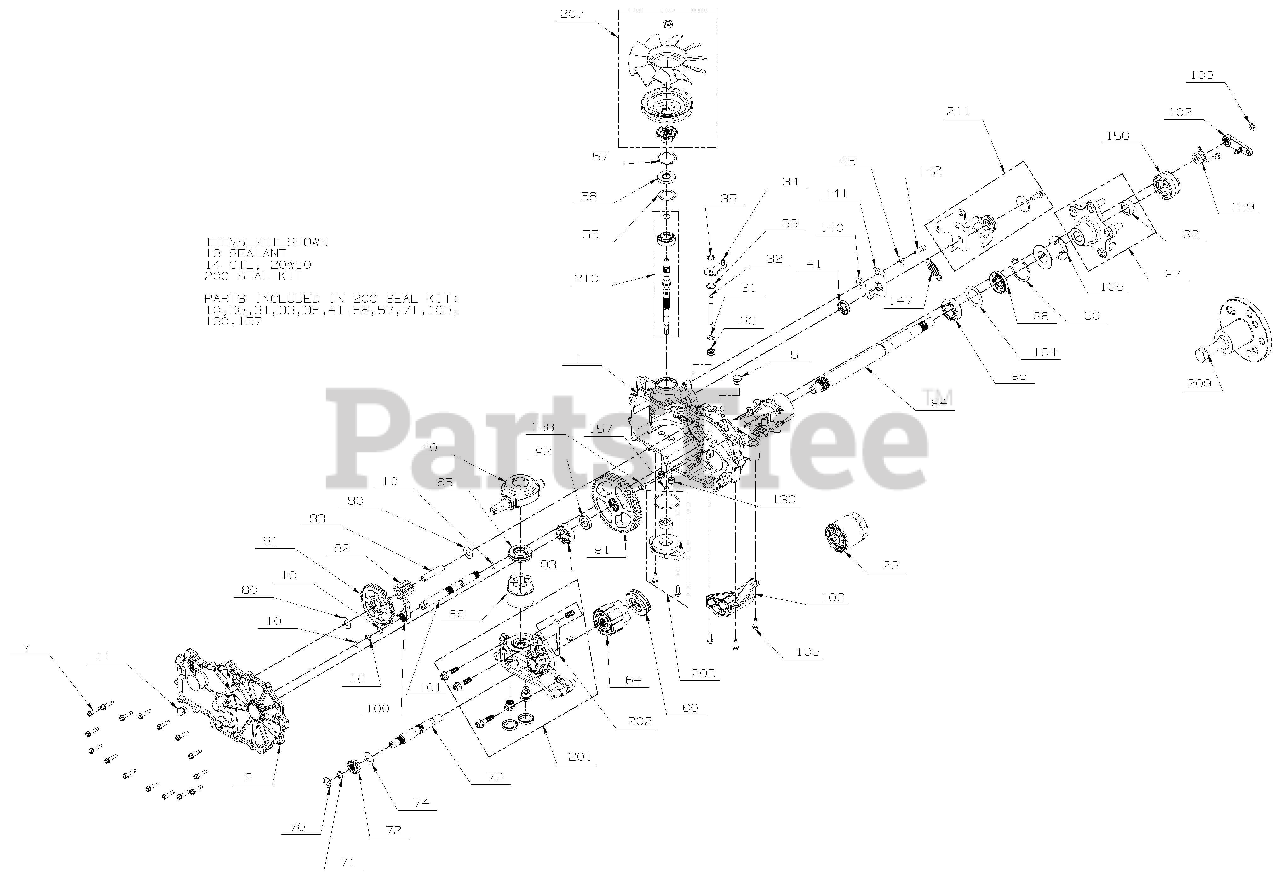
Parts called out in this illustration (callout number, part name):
1	KIT, MAIN HOUSING, RH, CHARGE, CONTROL
2	KIT, SIDE COVER RH
7	SCREW,HEX WASHER 1/4-20X1.125
13	SEALANT TUBE 10.1OZ.
23	OIL FILTER, TRANSMISSION
30	SEAL, LIP .375X.75X.25
31	RING. RETAINING
33	RING, RET .750
34	ARM, BYPASS
35	RING, RTNG .
40	TRUNNION, SWASHPLATE
41	SEAL, LIP 18X32X7
45	WASHER
55	WASHER 1.23X1.56X.04
56	SEAL, LIP 17X40X7
57	RING, RET 1.56 INT
60	HG THRUST BEARING (51462)
64	HG 16CC CYLINDER BLOCK (71579)
65	HG THRUST BLOCK (53502)
69	HG SEVEN PISTON BLOCK (71971)
70	WASHER .63X1.0X.05
71	RING, RET 62 EXT
73	SHAFT, MOTOR
74	WASHER .71 X 1.16 X .04
80	WASHER .5X1.0X.032
83	JACK SHAFT (PIN)
90	RING, RETAINING
93	KIT, BEARING
94	SHAFT, AXLE
95	BEARING, BALL 25.4 X 52 X 15
96	SEAL, LIP
97	HUB, HYDROGEAR P/N 71691
99	NUT, HEX, LOCK 3/4-16
100	PAWL, BRAKE
101	SHAFT, BRAKE
102	KIT, BRAKE ARM RIGHT HAND
105	HFHCS 1/4-20X.75
106	GUARD, FILTER, RH
140	SPACER
141	ARM, NEUTRAL RIGHT
142	SHCS 5/16-24X1 PATCH
147	RTN SPRING HG 51605
156	CAP, AXLE
158	MAGNET, RING
159	SPRING, TORSION CCW
164	WASHER, 1.355 x 2.035 x .021 FLAT
200	HG SEAL KIT (71976)
201	KIT, CENTER SECTION RH CHARGE
202	KIT, CHARGE RELIEF
203	KIT, CHARGE PUMP
207	KIT, FAN/PULLEY
209	HUB PULLER 4 BLT HYDGEAR 71459
210	INPUT SHAFT HG 71978
211	RTN KIT HYDROGEAR P/N 71597
